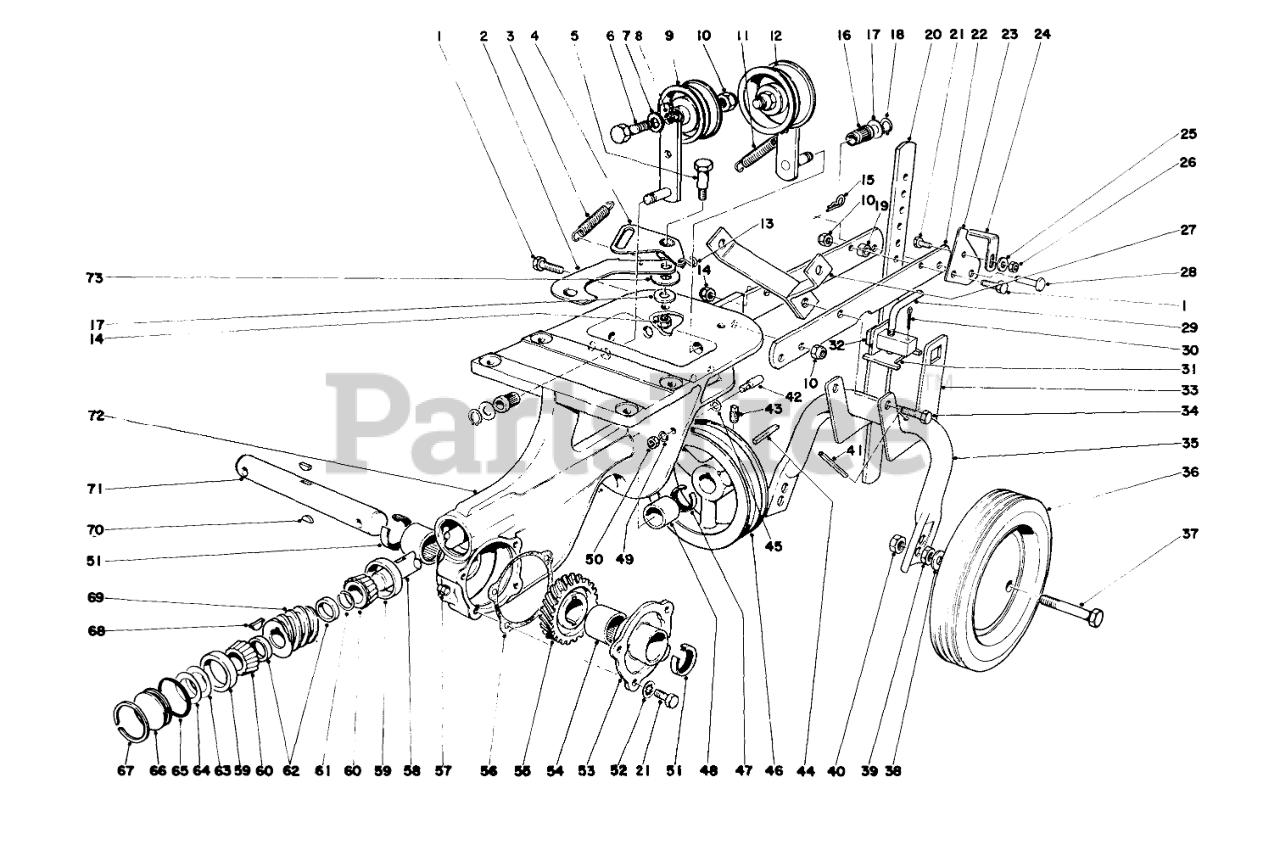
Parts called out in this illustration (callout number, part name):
1	SCREW-HH
2	Rev. Link
3	Spring
4	Bellcrank
5	SCREW-SHOULDER, HH
6	SCREW-HH
7	WASHER-FLAT
8	Idler
9	PULLEY IDLER
10	NUT-LOCK, CONE
11	Spring
12	PULLEY-IDLER
13	S Hook
14	NUT-LOCK, CONE
15	PIN-COTTER, HAIR
16	IDLER BRG
17	WASHER-PLAIN
18	RING-RETAINING, EXT
19	Spacer
20	DEPTH GAGE
21	SCREW-HH
22	Drawbar
23	Hinge Latch
24	Drag Bar Latch
25	WASHER-FLAT
26	NUT-LOCK, CONE
27	Handle Support
28	TINE PIN
29	Handle Jack
30	PIN-COTTER
31	Jack Plate
32	Jack Nut
33	Axle Saddle
34	SCREW-HH
35	Axle Yoke
36	Wheel
37	SCREW-HH
38	WASHER-FLAT
39	NUT-JAM
40	1/2-13 CONELOCK NUT
41	PIN-SPRING
42	Belt Guide
43	SCREW-SET, HSH
44	KEY-SQUARE
45	WASHER-FLAT
46	Pulley
47	SEAL-OIL
48	BUSHING
49	WASHER-LOCK/EXT
50	NUT-JAM
51	SEAL-OIL
52	WASHER-LOCK
53	Cover
54	Bearing
55	WORM WHEEL
56	GASKET
57	PLUG-PIPE, SQH
58	WORM SHAFT
59	BEARING-ROLLER, CUP
60	BEARING-CONE
61	RETAINER RING
62	SPACER
65	O-RING
67	INTRNL RETAINING RING
68	KEY-WOODRUFF
69	WORM GEAR
70	KEY-WOODRUFF
71	WORM WHEEL SHAFT
72	Chassis
73	WASHER-FLAT
